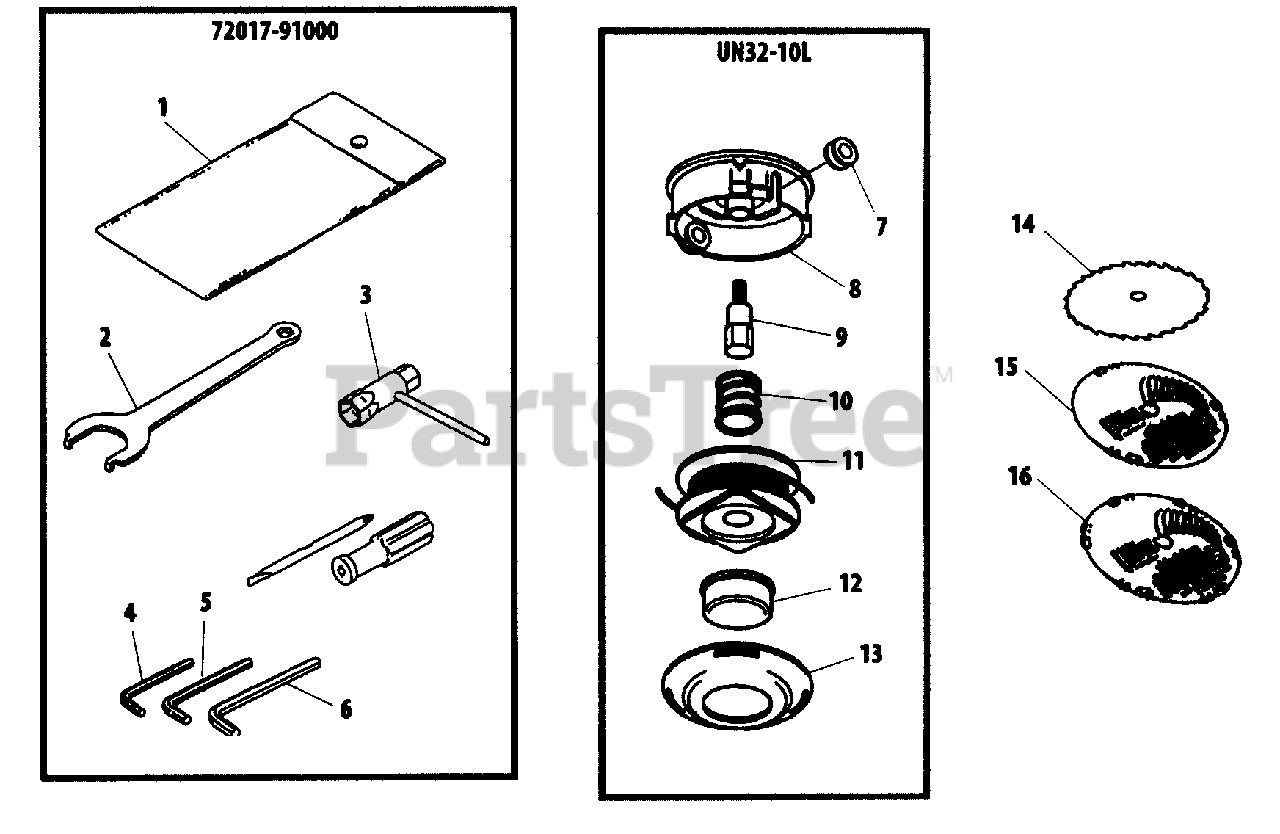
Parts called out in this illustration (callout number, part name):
1	BAG, TOOL
2	SPANNER
3	T-WRENCH - 17X19mm
4	HEX KEY - 4mm
5	HEX KEY - 6mm
6	HEX KEY - 3mm
9	SHAFT BOLT 10MM LH
14	BLADE - 30 TOOTH -- 9" (22cm)
15	BLADE - 6 TOOTH -- 9" (22cm)
16	BLADE - 12 TOOTH -- 9" (22cm)
72017-91000	TOOL KIT
UN32-10L	TRIMMER HEAD ASSY
